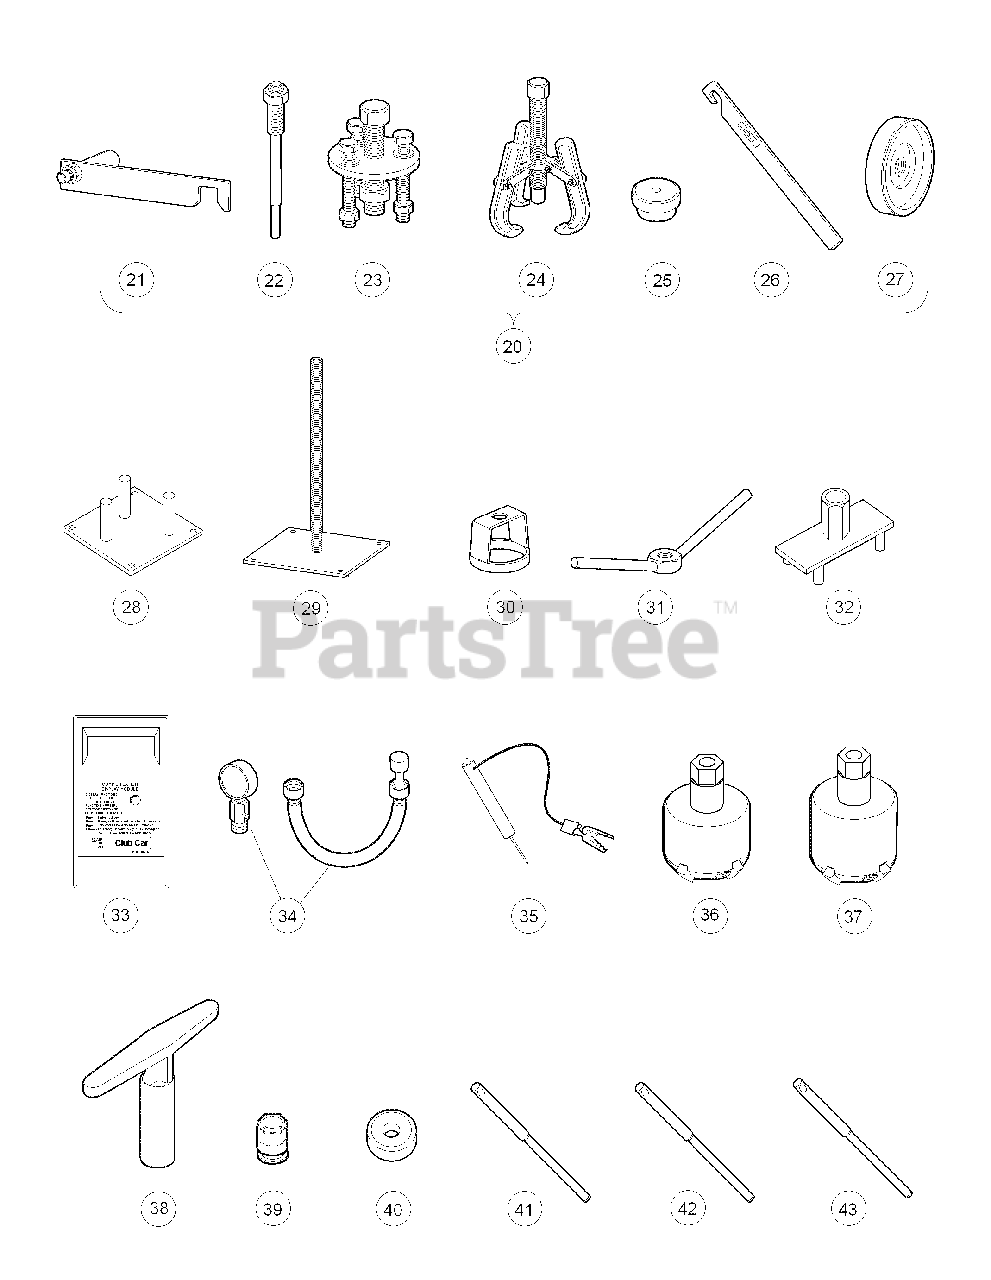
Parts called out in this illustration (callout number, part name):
20	Clutch Tool Kit
21	Clutch Alignment Tool
22	Drive Clutch Puller
23	Drive Clutch Hub Puller
24	Driven Clutch Cam Puller
25	Driven Clutch Puller Plug
26	Drive Clutch Holder Tool Assembly
27	Press Weldment
28	Drive ClutchFixed Sheave Tool
29	Driven Clutch Spring Compression Base
30	Driven Clutch Spring Compression Collar
31	Driven Clutch Spring Compression Nut
32	Drive Clutch Spider Removal Tool
33	Communication Display Module
34	Compression Gauge and Adapter
35	Continuity Tester
36	Cutter, Valve Seat, #122
37	Cutter, Valve Seat #115
38	Wrench, T, #505
39	Adapter, T-Wrench
40	Cutter, Valve Seat, 60 Degree
41	Pilot, 66 MM
42	Pilot, 662 MM
43	Pilot, 665 MM
